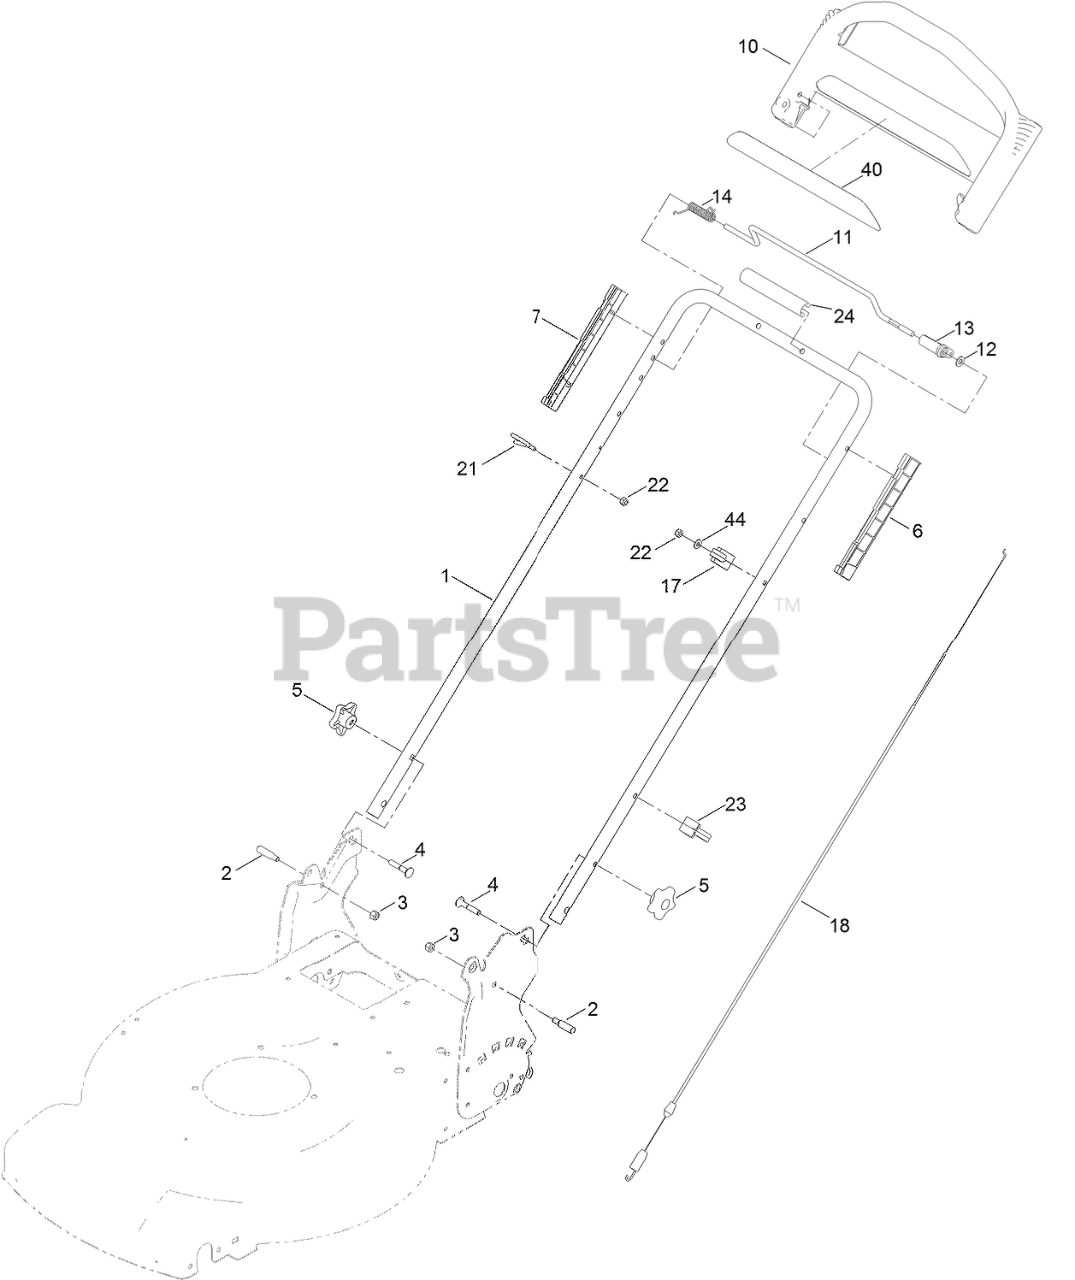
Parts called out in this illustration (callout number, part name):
2	BOLT-SHOULDER
3	NUT-HEX
4	SCREW-CARR
5	KNOB-HANDLE
6	GUIDE-LH
7	GUIDE-RH
10	HANDLE-CONTROL
11	BAR-CONTROL, TRACTION
12	WASHER-PLAIN
13	LEVER-TRACTION
14	SPRING-TORSION
17	ANCHOR-CABLE
18	CABLE-TRACTION
21	GUIDE-ROPE
22	NUT-HEX
23	GUIDE-CABLE
24	HANDLE-COVER
40	DECAL-HANDLE
44	WASHER-FLAT
